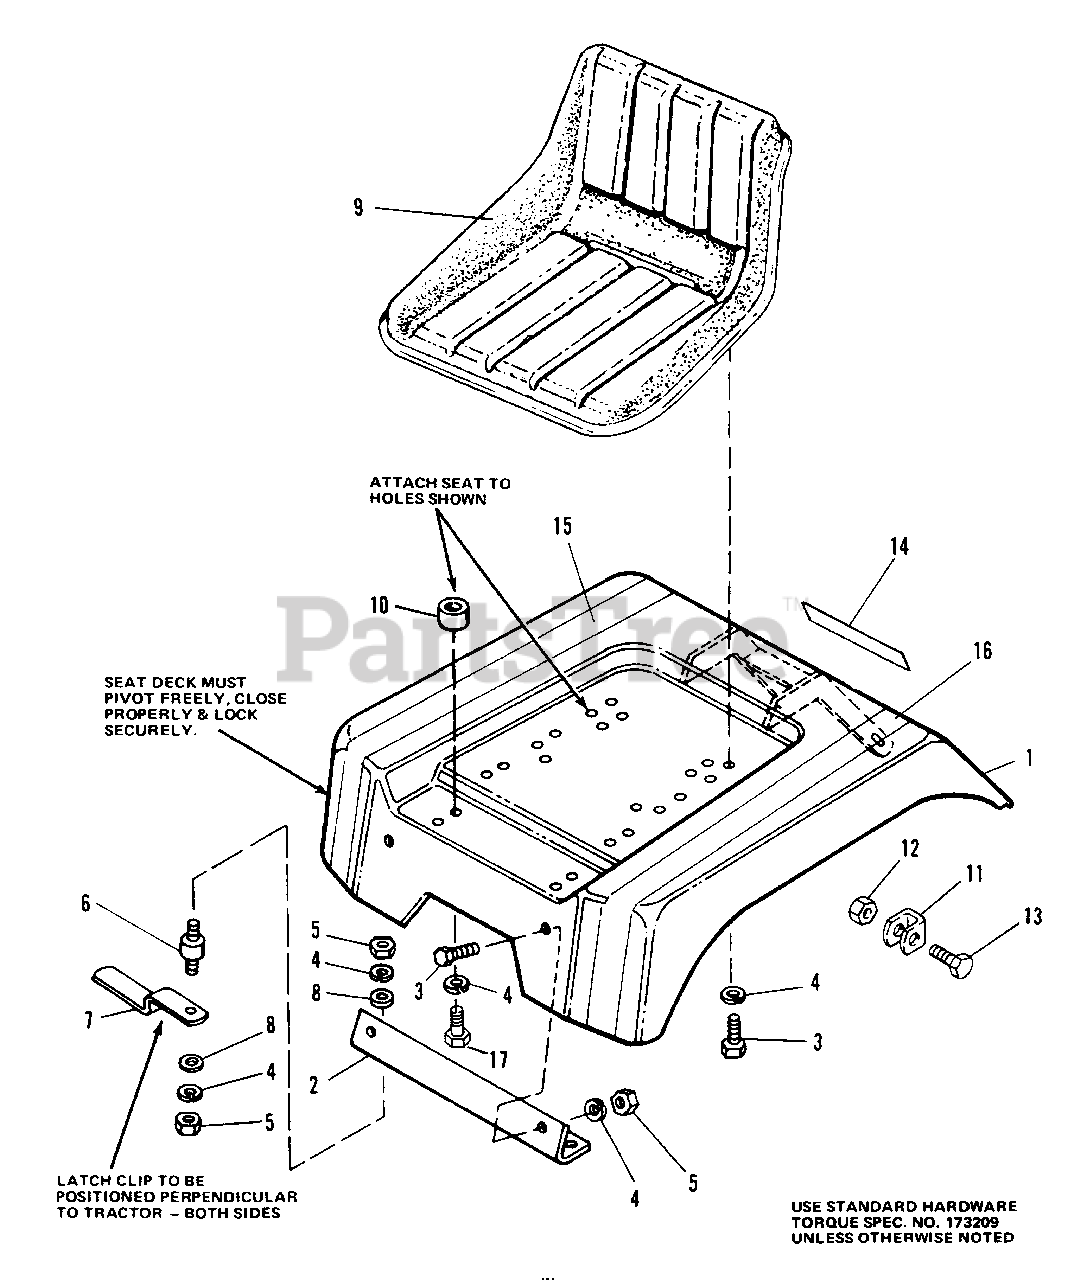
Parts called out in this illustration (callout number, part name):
1	SEAT, Deck
2	BRACKET, Frt. Seat Deck
3	CAPSCREW, 5/16-18 x 5/8
4	LOCKWASHER, 5/16
5	NUT, Hex, Full, 5/16-18
6	CONNECTOR, Cushion
8	WASHER, 1/4
11	STOP, Seat Deck
12	LOCKNUT, Hex, 3/8-16
13	CAPSCREW, Hex, 3/8-16 x 1-1/4
14	DECAL, Simplicity
15	DECAL, Stripe, R.H.
16	DECAL, Stripe, L.H.
17	CAPSCREW, Hex Hd., 5/16-18 x 1 1/4
